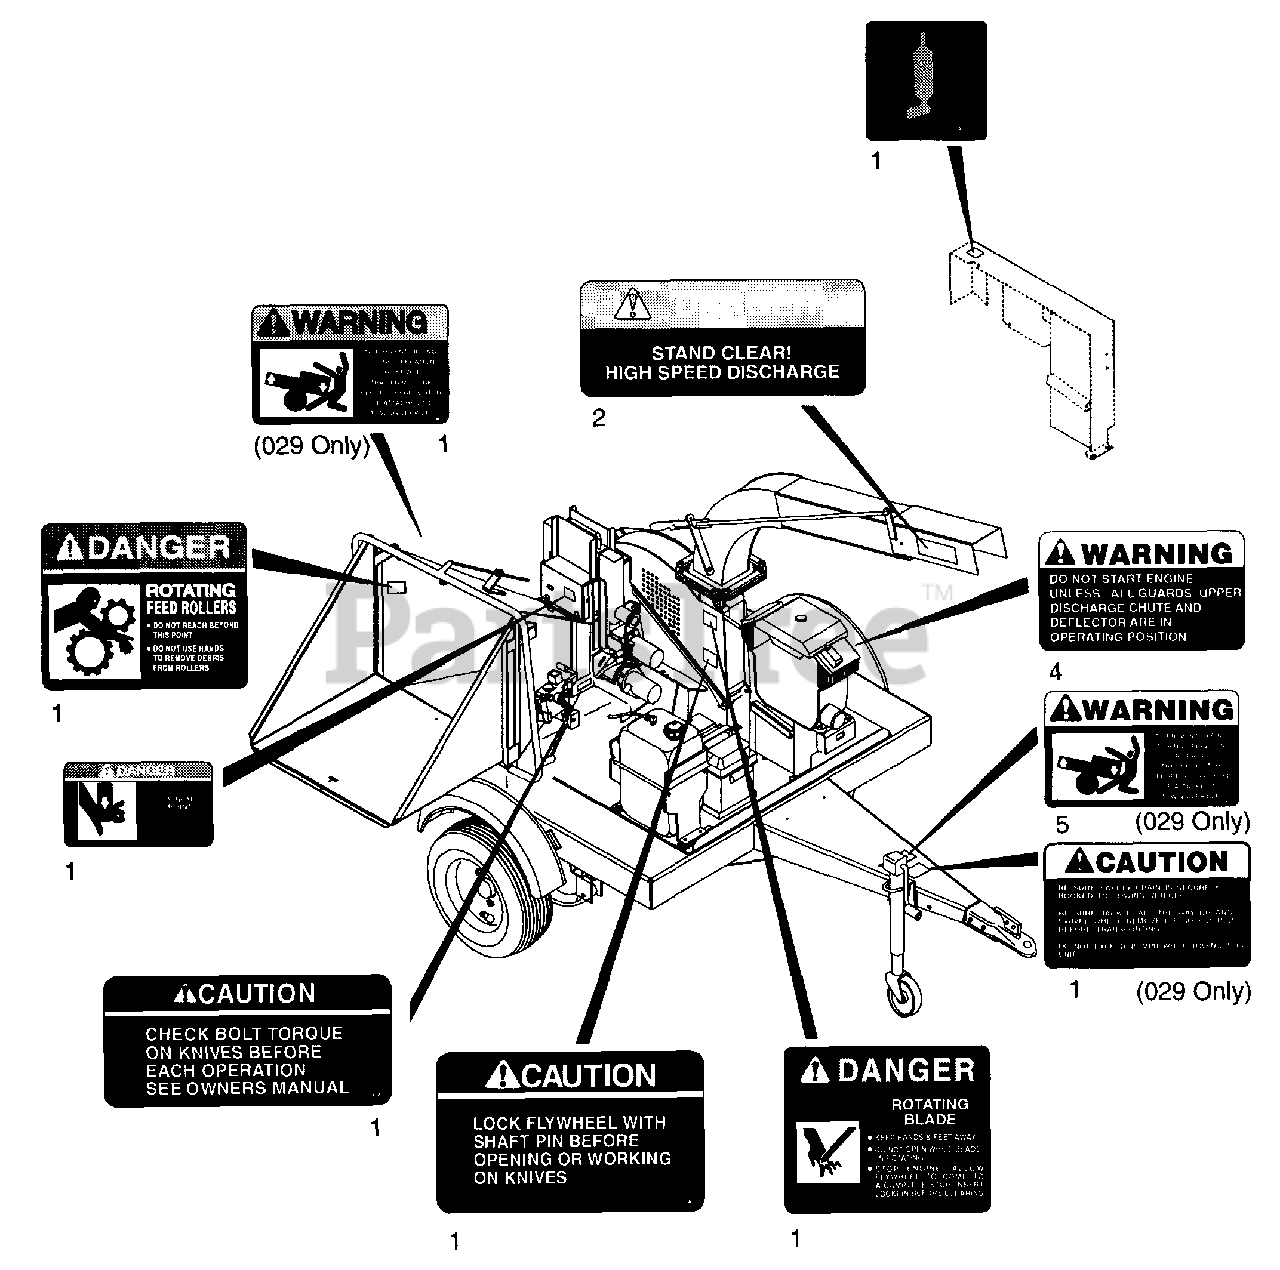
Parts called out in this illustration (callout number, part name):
1	Decal Set
2	Decal Set Large Chipper
4	Decal - Warning, Start Engine
5	Decal - Warning, Tipping
7	Decal - Pro Chip 625LR
8	Decal - Warning, Protective
9	Decal - Hot Surface
